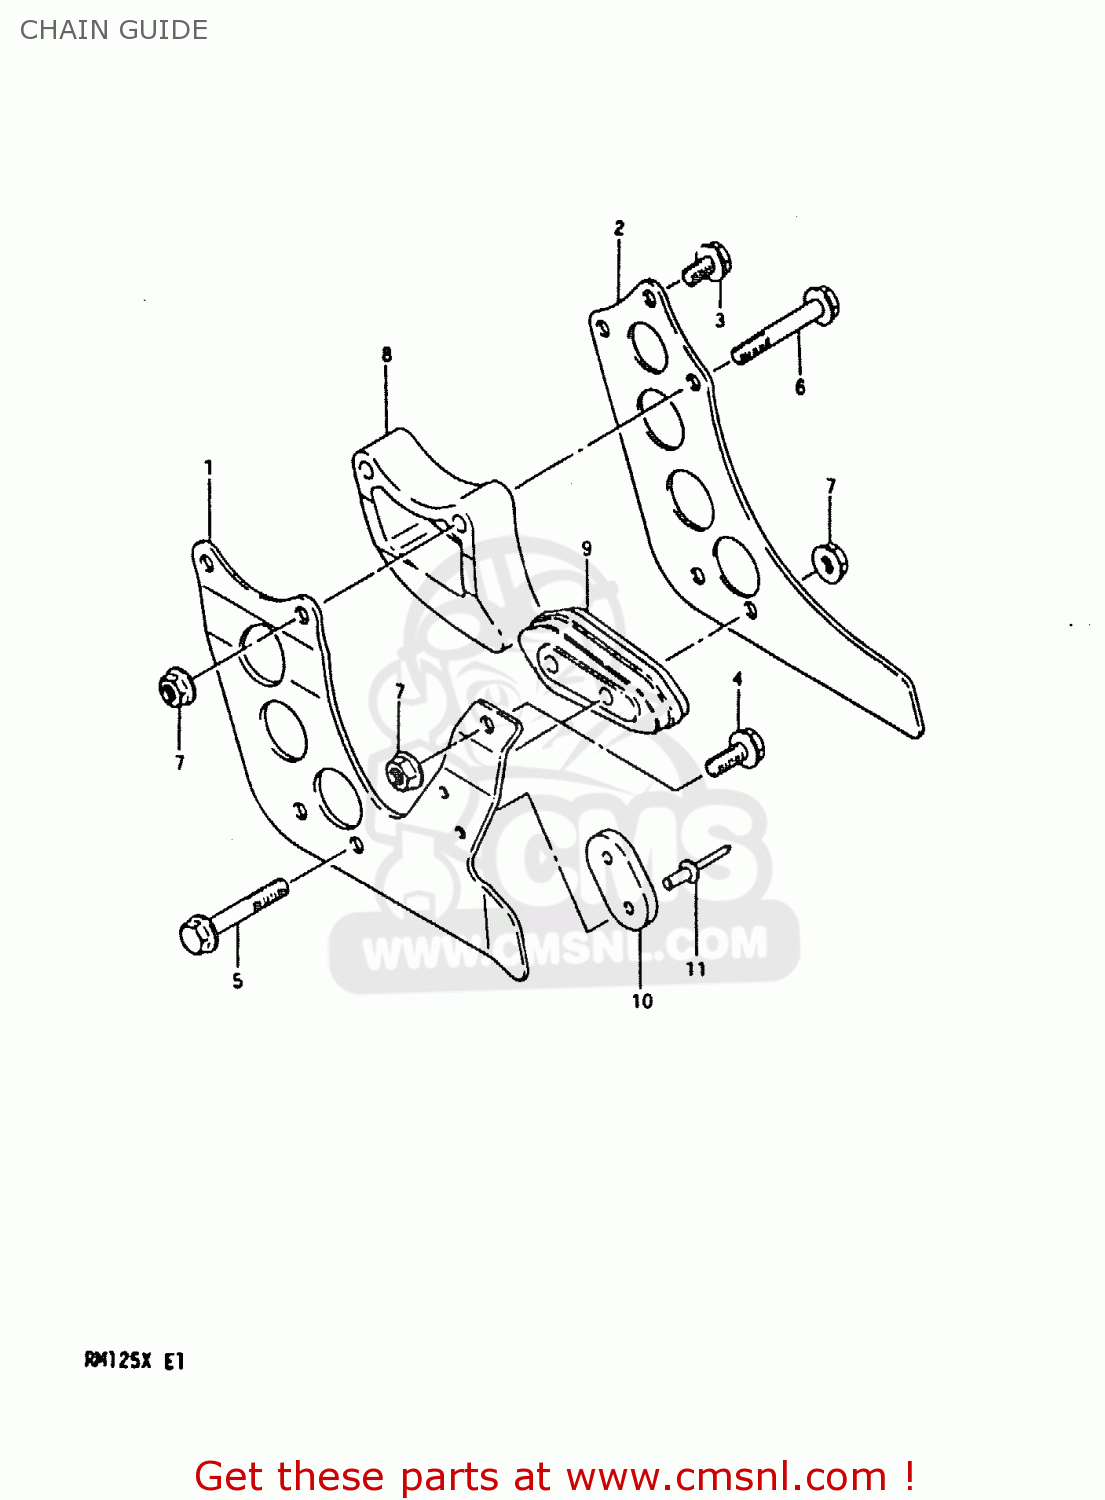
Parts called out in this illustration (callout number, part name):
1	PLATE,CHAIN GUIDE,OUTER
2	PLATE,GUIDE CHAIN
3	BOLT
4	BOLT
5	BOLT
6	BOLT,UNDER
7	NUT
8	DEFENSE,CHAIN GUIDE UPR
9	DEFENSE,CHAIN GUIDE
10	PAD,DRIVE CHAIN GUIDE
11	RIVET
